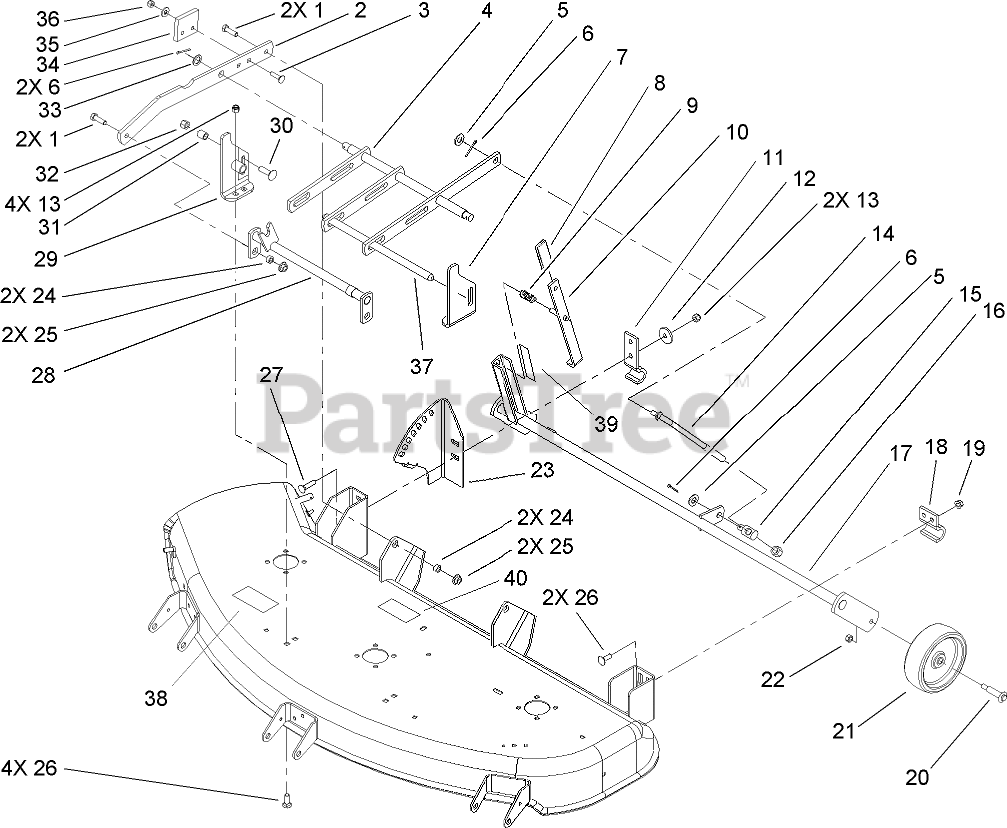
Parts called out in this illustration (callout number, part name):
1	SCREW-HH
2	BAR-DRAFT
3	SCREW-CARR
4	BAR-LEVELER
5	WASHER-FLAT
6	PIN-COTTER
7	BRACKET-FRONT DECK, LH
9	SPRING-COMPRESSION
10	LEVER-HOC
11	BRACKET-PIVOT
12	WASHER-SUPPORT
13	NUT-LOCK, NI
14	ROD-ADJUSTMENT
15	TRUNNION
16	NUT-LOCK, NI
17	Wheel Support-48 In
19	NUT-FLANGE
20	BOLT-SHOULDER
21	WHEEL
22	NUT-HEX
23	Bracket-Quadrant,48 In
24	SPACER
25	LOCKNUT-FLANGE
26	BOLT-CARR
27	SCREW-CARR
28	HITCH ASM
29	BRACKET-FRONT DECK, RH
30	BOLT-CARR
31	SPACER
32	NUT-LOCK, NI
33	WASHER-FLAT
34	BUMPER
35	WASHER-FLAT
36	NUT-LOCK, NI
37	Shaft-Front
38	DECAL-BELT ROUTING, PTO
39	DECAL-HOC
40	DECAL-BELT ROUTING
